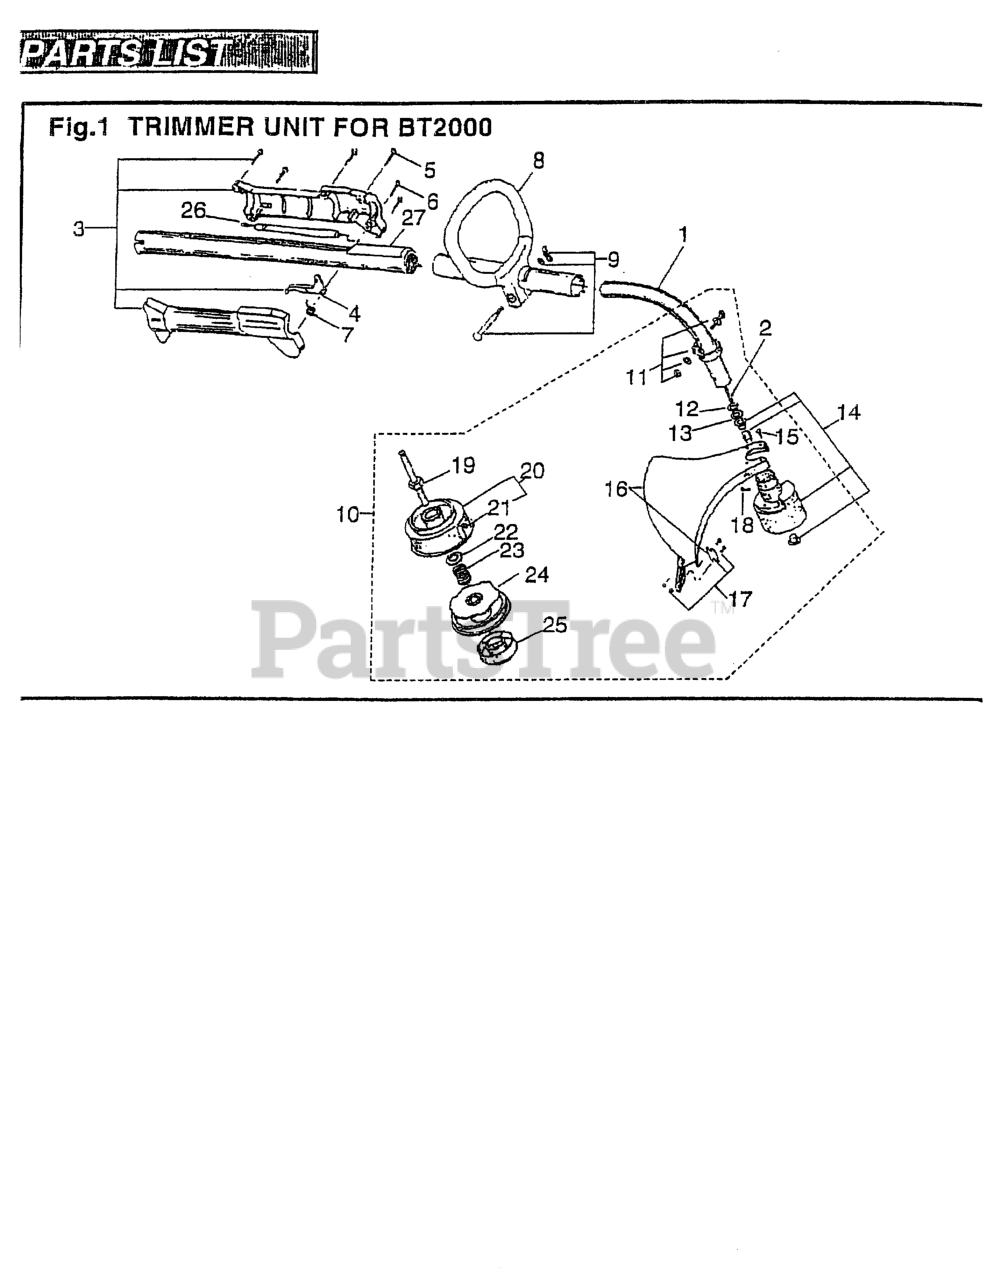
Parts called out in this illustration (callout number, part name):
1	SHAFT ASSEMBLY (BT)
4	LEVER, THROTTLE
5	SET SCREW, ANTI-ROTATION
7	SPRING, THROTTLE TRIGGER
10	CUTTING HEAD ASSEMBLY
11	CLAMP ASSY, LOWER
12	RING, RETAINING
13	WASHER
14	ASSY, BUSHING HOUSING
15	SCREW, GUARD MTG (SET)
17	BLADE ASSEMBLY
18	SET SCREW, ANTI-ROTATION
20	OUTER SPOOL ASSEMBLY
21	EYELET
22	WASHER, EYELET
26	CABLE ASSY, THROTTLE
27	LABEL, BT2000
